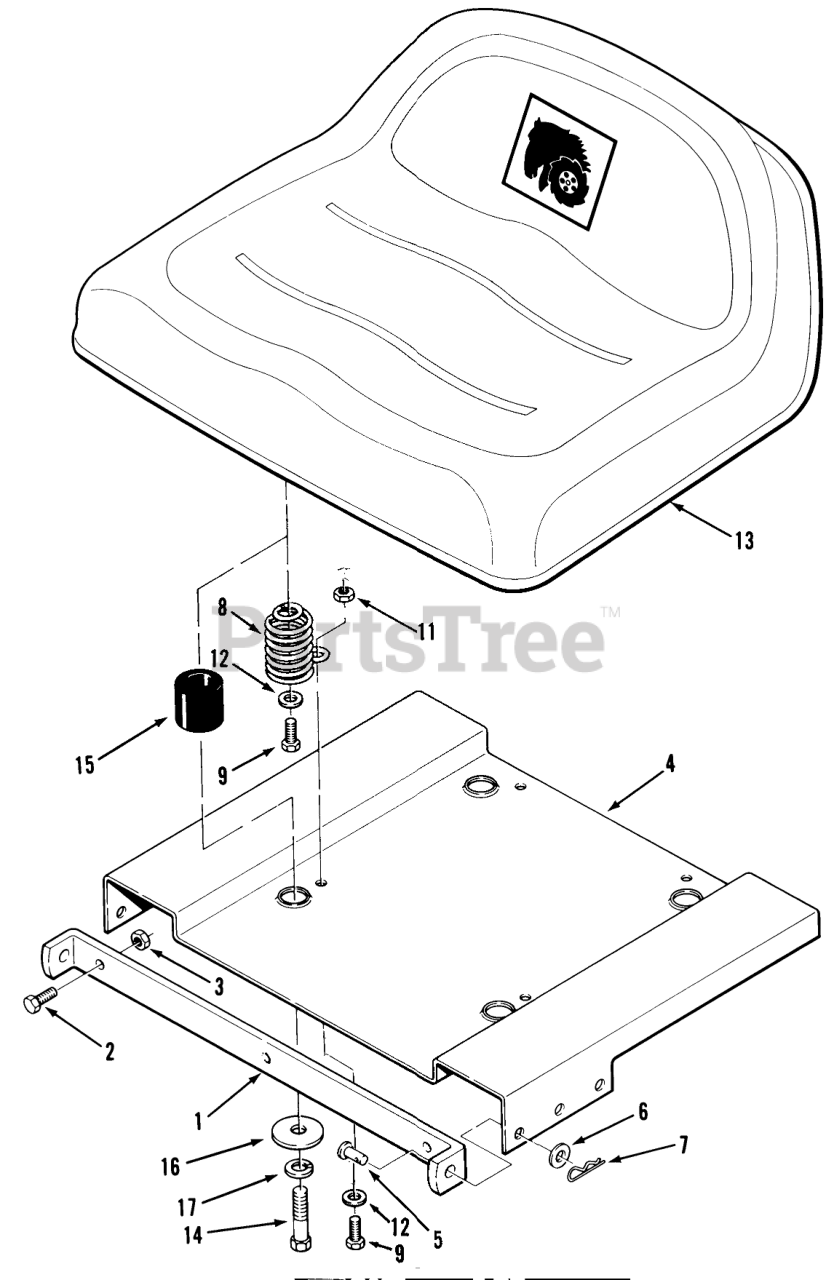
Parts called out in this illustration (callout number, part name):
1	BRACKET - SEAT MO R
2	Bolt
3	Nut
4	Seat Pivot Plate
6	WASHER-SPRING
7	Hairpin
8	SPRING SEAT
9	Bolt
11	Nut
12	WASHER 5/16 SAE
13	ASSY-SEAT
13	Seat
13	Seat 310-8
14	Bolt 5/16-18 x 2
15	SPACER SEAT B
16	WASHER
17	Lockwasher
